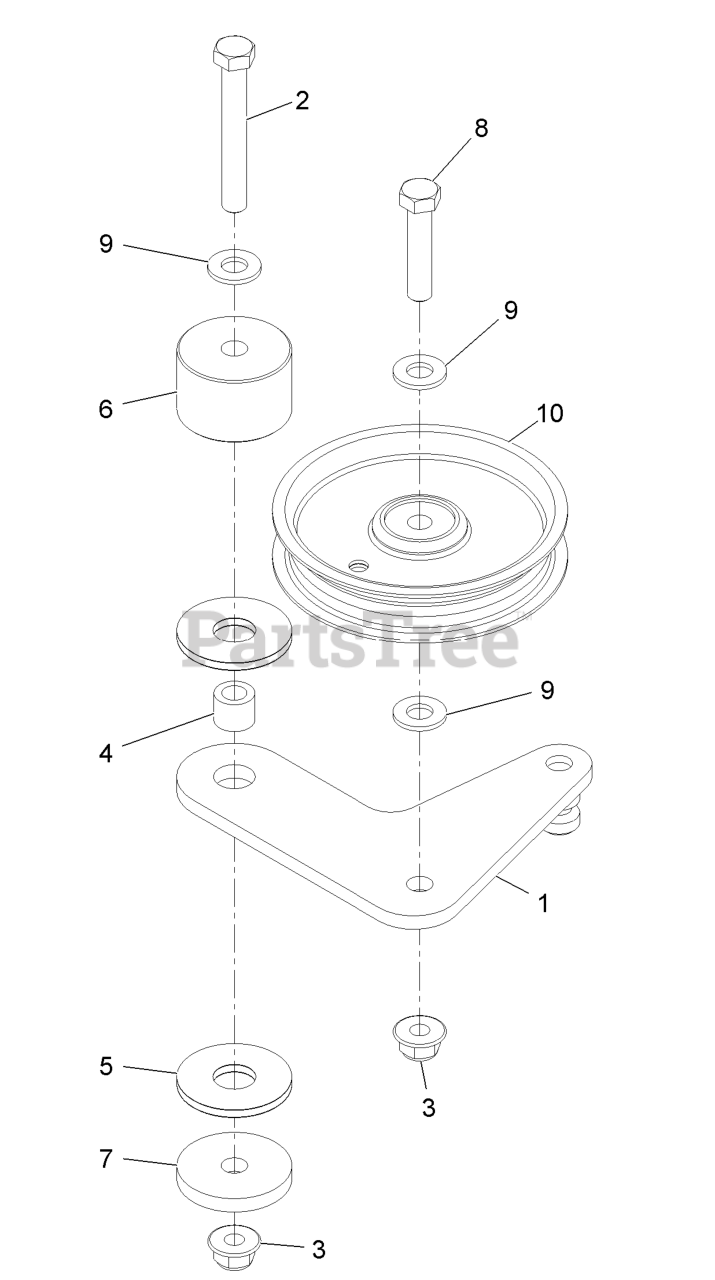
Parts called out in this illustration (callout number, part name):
1	PLATE-IDLER
2	SCREW-HH
3	NUT-HF, NI
4	BUSHING-LEVER, LIFT
5	WASHER-FRICTION, COMPOSIT
6	HUB-IDLER
7	WASHER-PLAIN
8	SCREW-HH
9	WASHER-FLAT
10	PULLEY-IDLER
